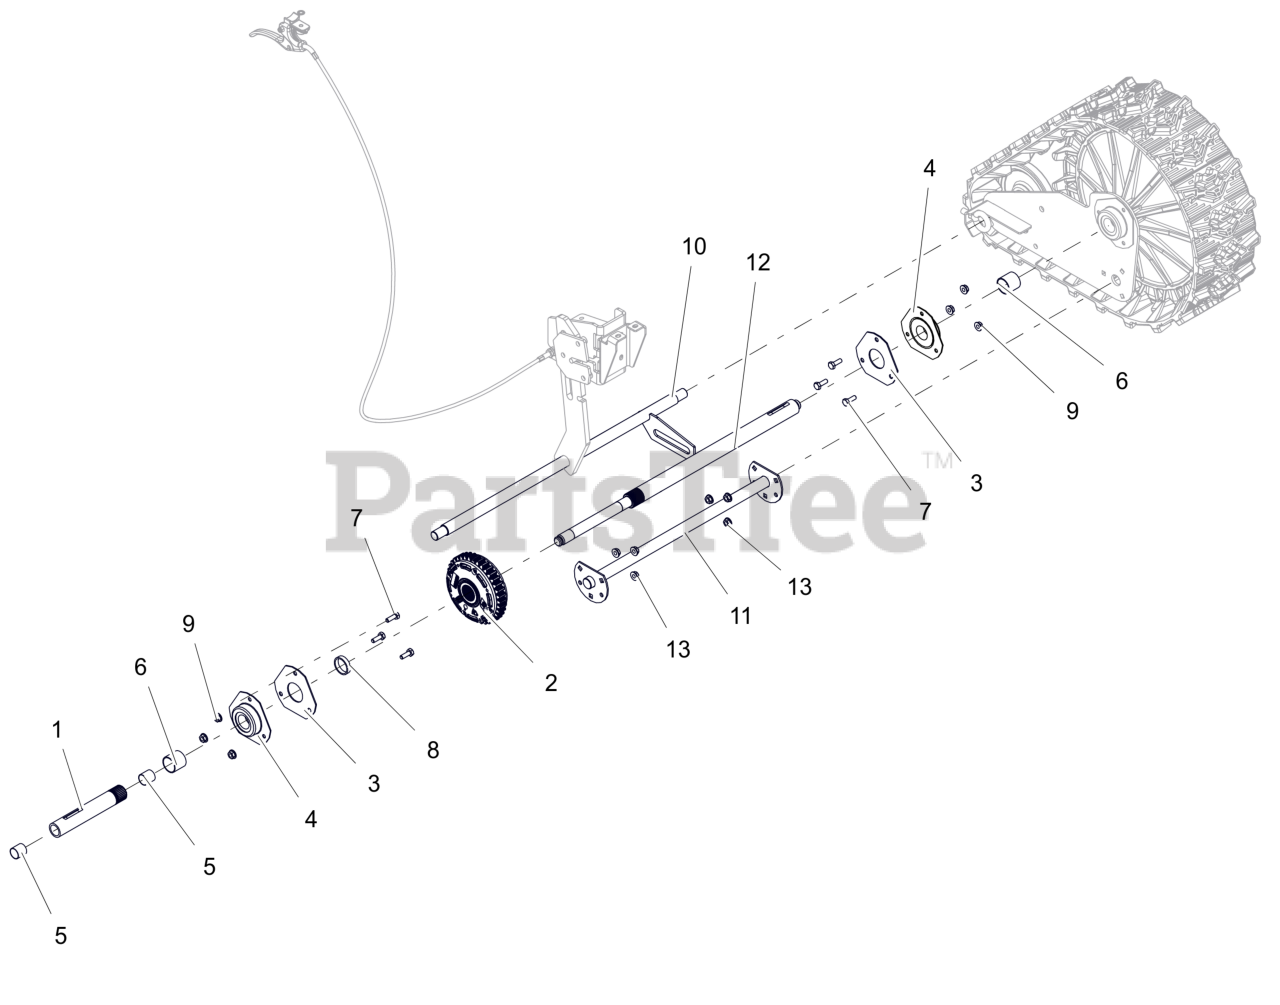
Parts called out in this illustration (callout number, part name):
1	AXLE, SHORT-W/BUSHINGS
2	DIFFERENTIAL, AUTOMATIC
3	PLATE, BEARING SPACER
4	BRG-FLG 1.003/1.000 3 BOLT
5	BSHG-SLV .706X.764X.75 BRZ
6	BSHG-SLV, 1.012X1.125X1.00
7	BLT, HEX .25-20X.75 G5 ZCC
8	BSHG, SLV 1.062X1.228X.268
9	NUT-LK-CTR-FLG .25-20 ZC120
10	AXLE, REAR-BWT WLDMT
11	SUPPORT, FRONT-BWT
12	AXLE, LONG-TRACK DIFFERENTIAL
13	NUT-LK-TOP-FLG .250-20 GF ZCC
